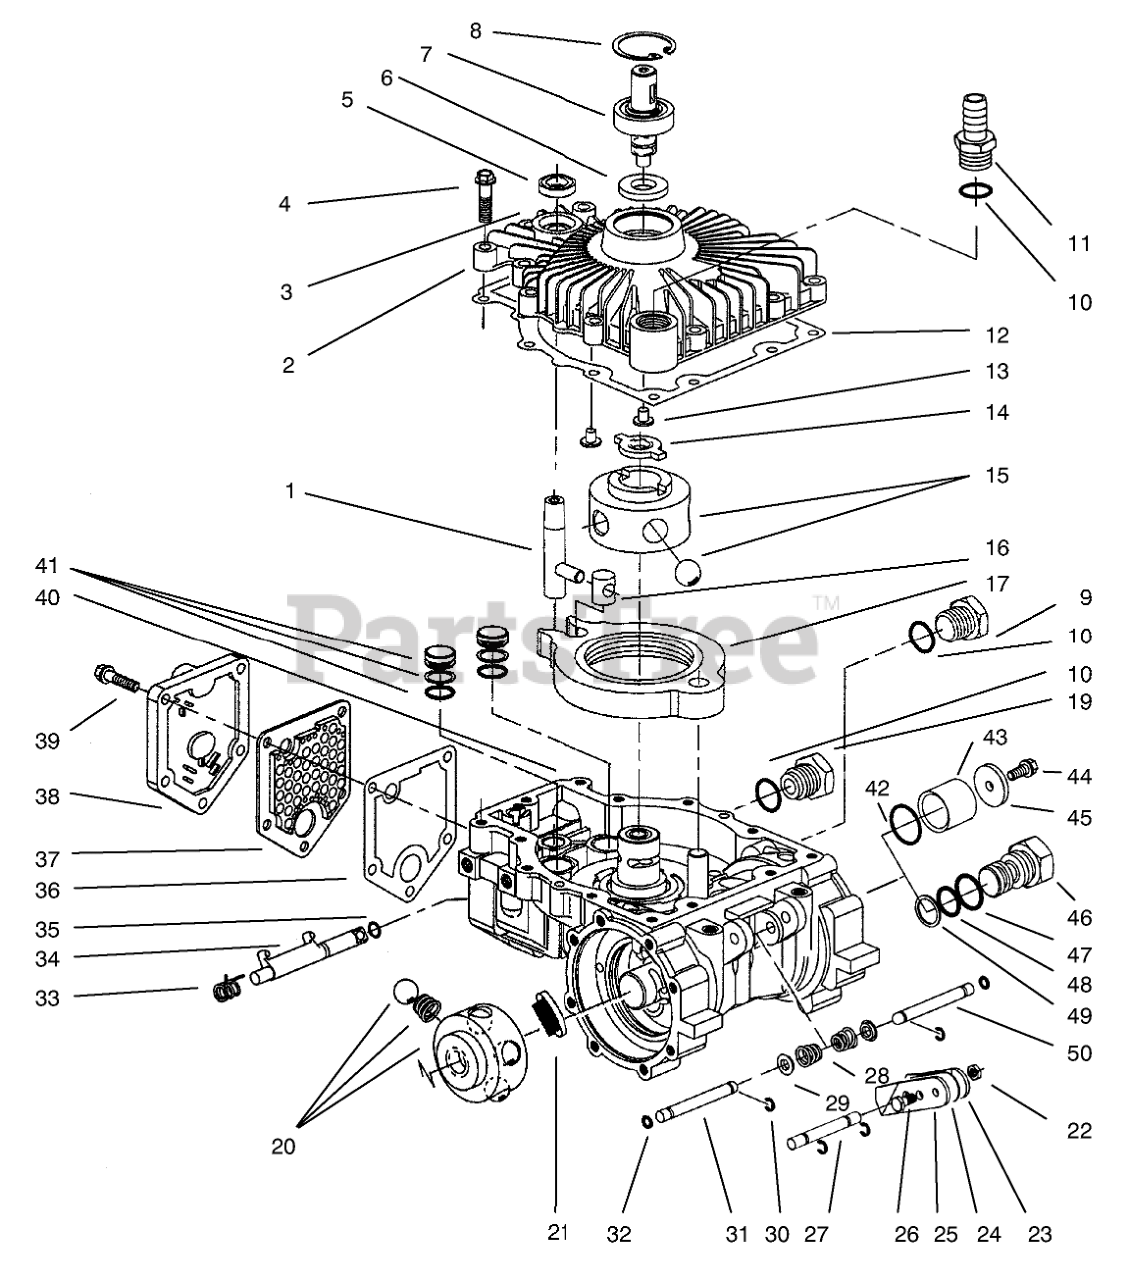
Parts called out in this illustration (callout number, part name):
1	CONTROL SHAFT
2	Cover Assembly (Incl. Ref.# 3, 5-8)
3	COVER
4	1/4-20 SCREW
5	SEAL-OIL
6	Seal
7	INPUT SHAFT
8	Retaining Ring
9	Plug Assembly (Incl. Ref. #10)
10	"O" RING SEAL
11	Fitting 90deg.
12	COVER GASKET
13	Button
14	DRIVE
15	PUMP ASM
16	INSERT
17	CAM RING ASM
19	ROTOR BALL ASM
20	ROTOR BALL ASM
21	FRICTION PAD
22	LOCKNUT
23	RH BRAKE LEVER
25	LH BRAKE LEVER
26	HEX HEAD SCREW
27	BRAKE SHAFT
28	CONICAL SPRING
29	SPRING BASE
30	RETAINING RING
31	PUSH ROD
32	QUAD SEAL
33	DUMP VALVE SPRING
34	DUMP VALVE BRACKET
35	SEAL "O" RING
36	FILTER GASKET
37	FILTER
38	VALVE COVER
39	1/4-20 HEX HEAD SCREW
40	HOUSING ASM
41	PISTON ASM
42	"O" RING SEAL
43	CUP SEAL
45	WASHER
47	"O" RING SEAL
48	"O" RING SEAL
49	BACKUP RING
50	PUSH ROD
